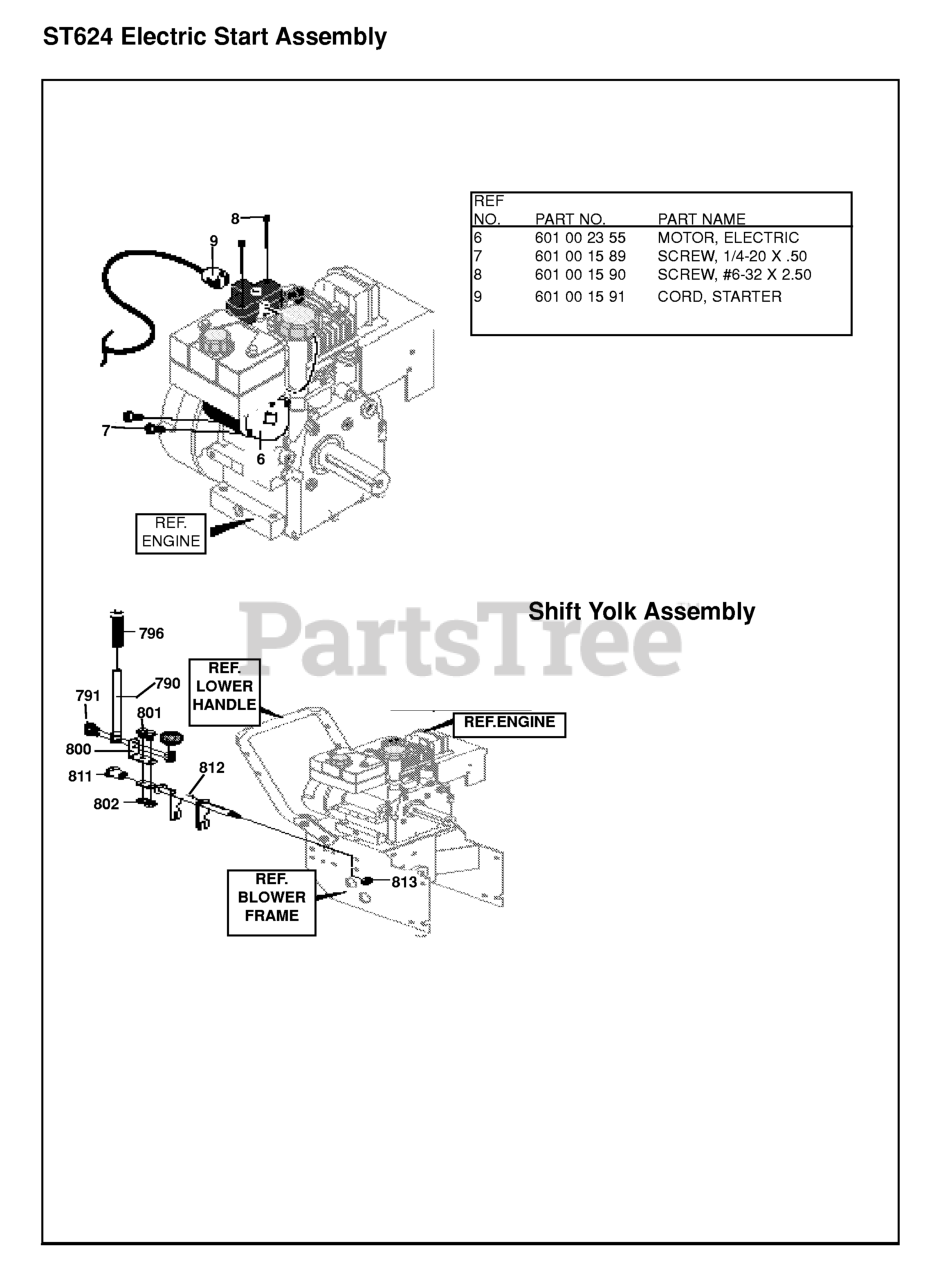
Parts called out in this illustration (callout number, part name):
6	ELECTRIC MOTOR
7	SCREW 1/4-20X.50 WASEMSTOR
8	SCREW #6-32X2.50
9	CORD, STARTER MOTOR
791	SCREW, 1/4-20X .75 HHC
796	KNOB, SLIP
800	LEVER, SPRING
801	SCREW, 1/4-20X .75 HHC
811	FLANGE BEARING
812	ROD, ASSY YOKE
813	NUT, 3/8-16 REGHXCTRLK
